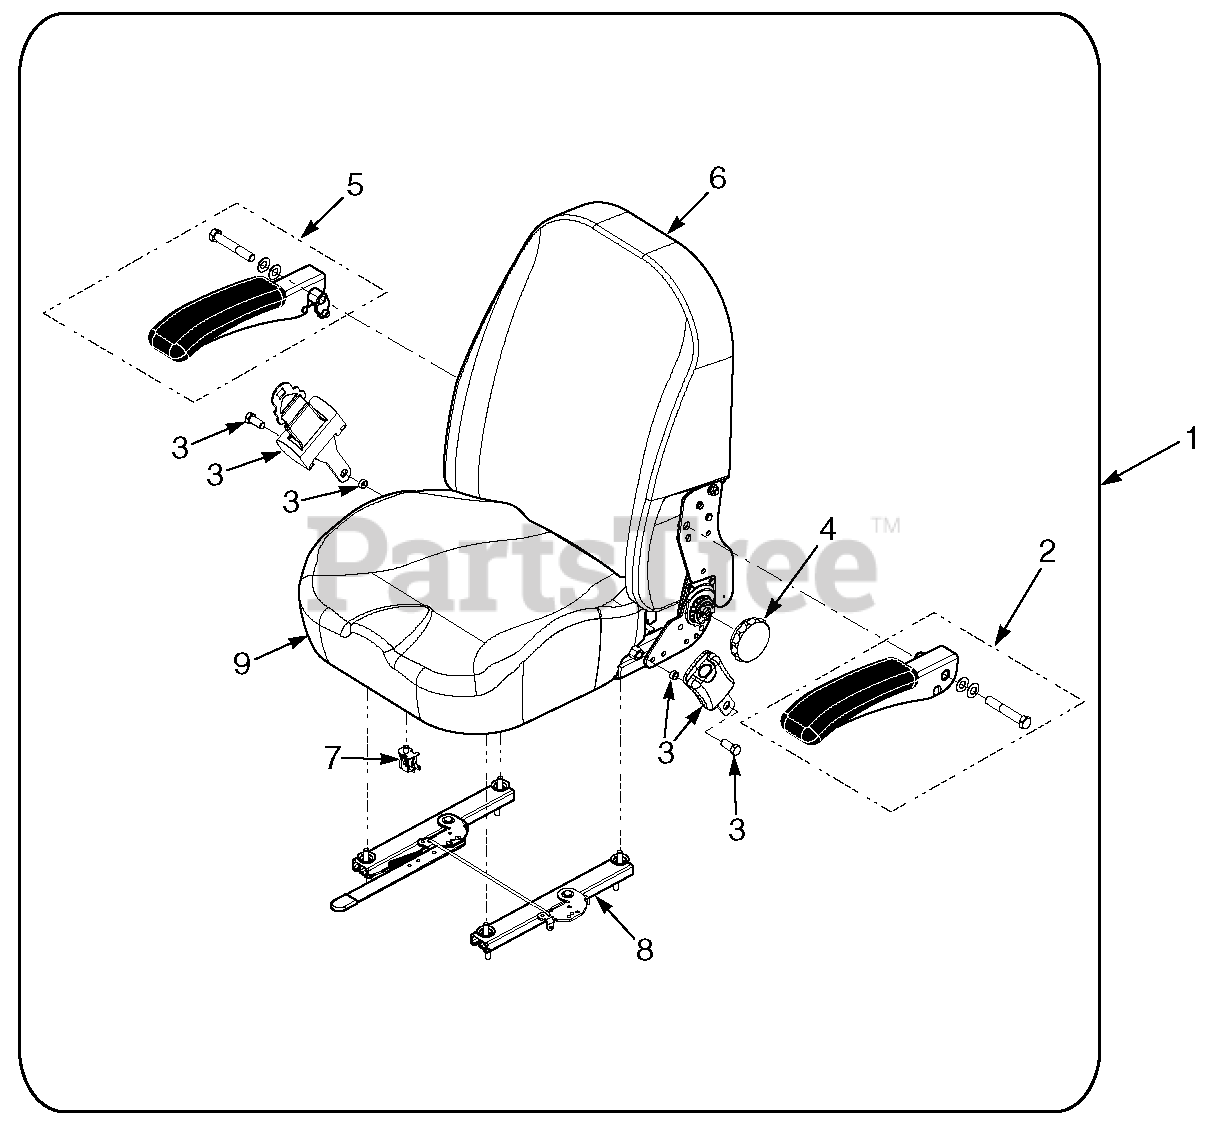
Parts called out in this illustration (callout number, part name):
1	Seat Assembly - SCZ
2	Armrest Kit, LH
3	Seat Belt Kit
4	Recliner Knob
5	Armrest Kit, RH
6	Back Cover
7	Seat Switch
8	Track Kit
9	Cushion Cover
